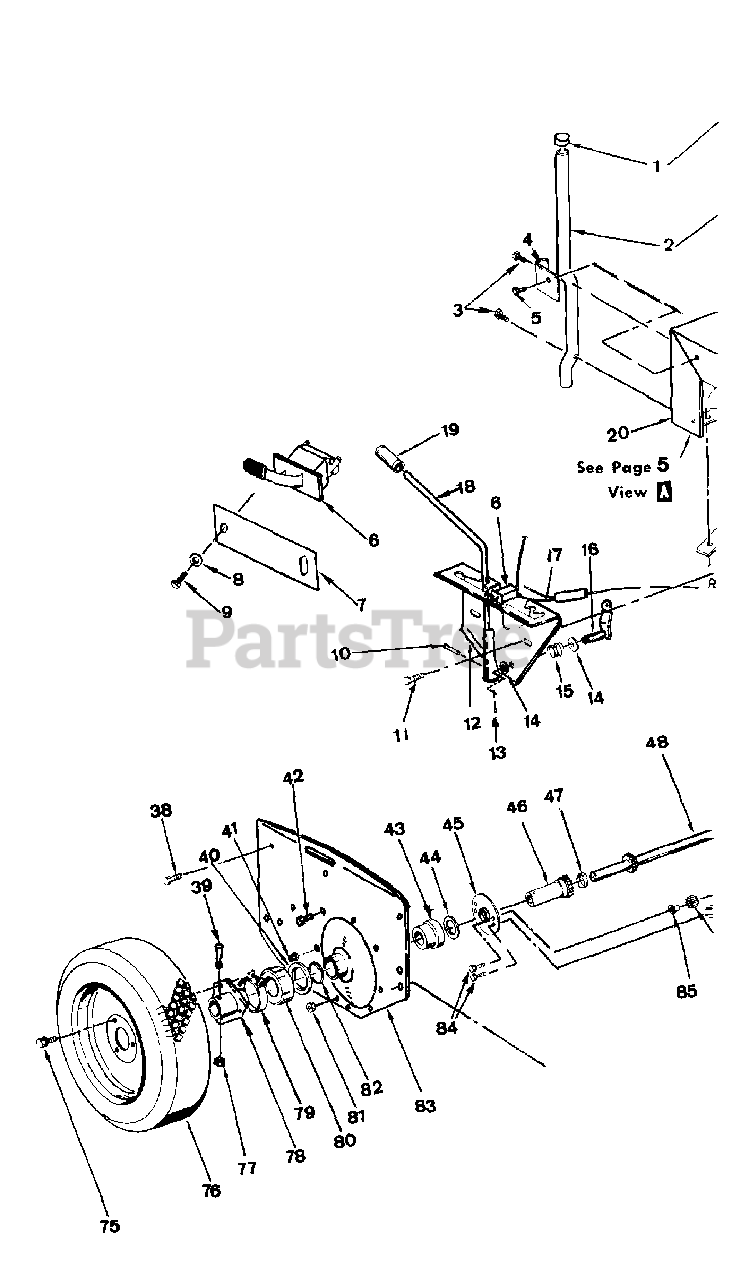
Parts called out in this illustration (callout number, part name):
1	Cap
2	Bumper
3	Bumper Bolt
5	5/16-18 x 5/8 HWST
6	M. P. E. Switch Assembly
7	Switch Protector
8	No. 10 SAE Washer
9	SCREW, #10-24 x 1/2" Hex Washer Self-Tap (Torx)
10	Clevis Pin
11	5/16-18 x 5/8 HWST
12	Shift Detent
13	3/32 x 3/4 Cotter Pin
14	Thrust Washer
15	Spring
16	Shift Handle Arm
17	Mower Clutch Wire
18	Shift Handle
19	Grip
20	Main Case
38	5/16-18 x 5/8 HWST
39	Wheel Bolt, R. H. Axle
40	Oil Seal
41	5/16 Flange Lock Nut
42	1/4-20 x 5/8 Self Tapping Screw
43	Bearing
44	Thrust Washer
45	Differential Plate
46	Short Axle Assembly
47	SPACER, Differential (1.25" ID x .425 Wide)
48	Long Axle Assembly
75	Lug Bolt
76	Wheel and Tire Assembly
77	5/16-24 Lock Nut, GR. 5
78	Wheel Hub, Right Hand
79	Boot Clamp
80	Seal Cap, Right Hand
81	NUT, 5/16-24 Hex
82	Clamp Ring
83	Fender, Right Hand
84	5/16-24 x 1-5/8 Hex Head Lock Cap Screw
85	Pinion Spacer
